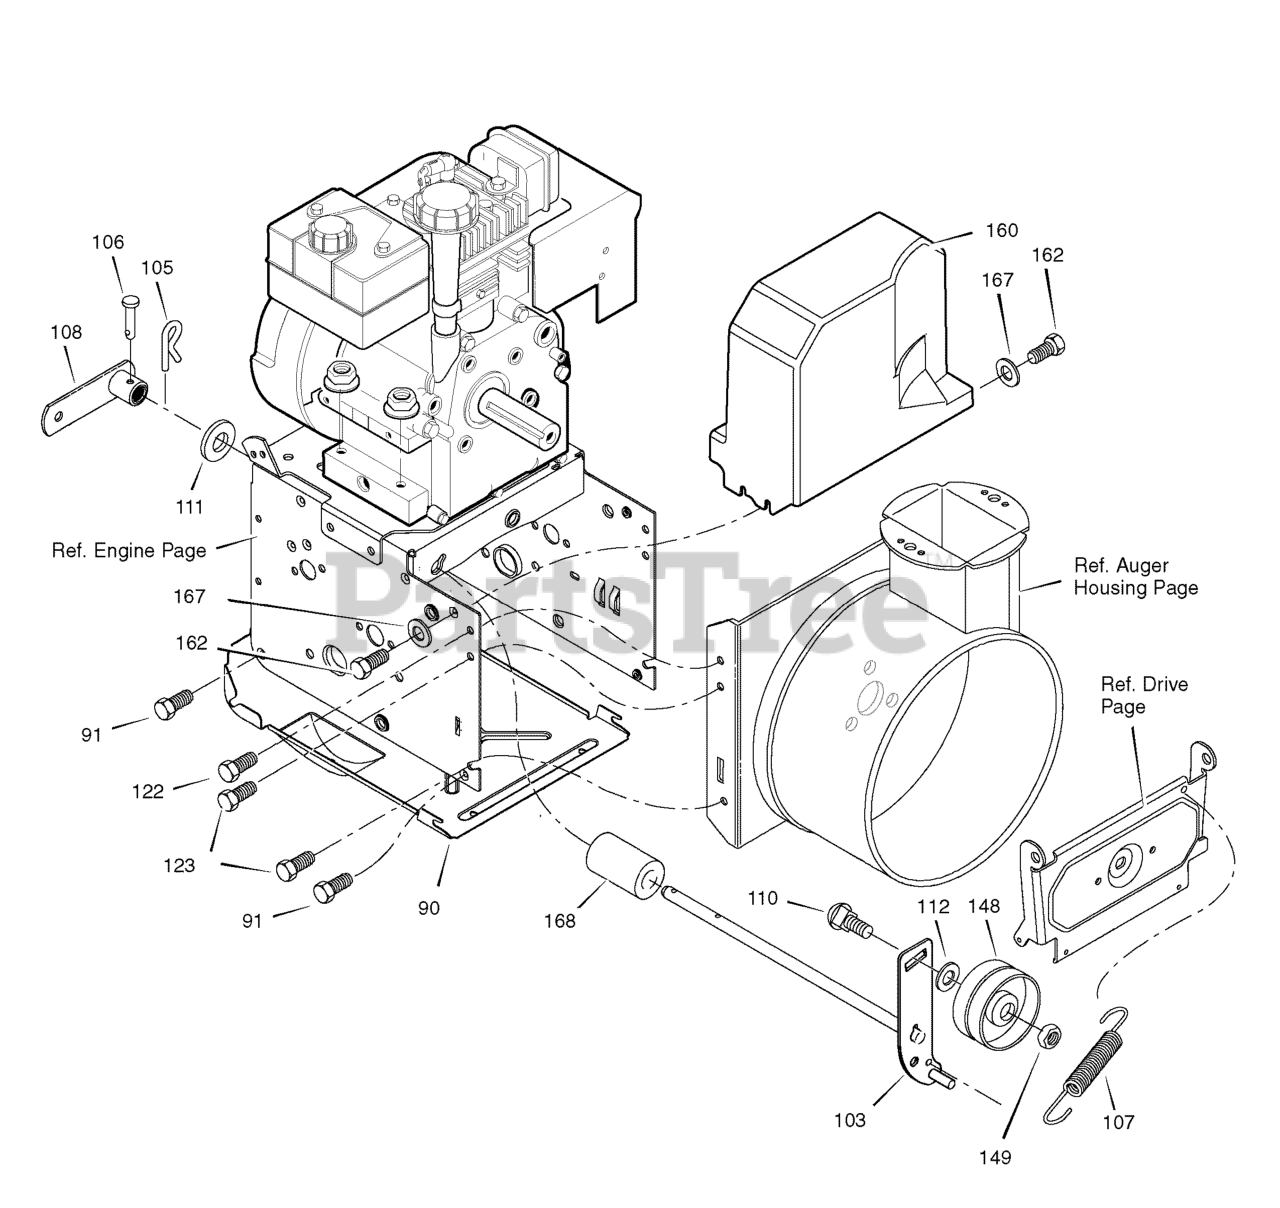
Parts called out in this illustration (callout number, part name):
90	COVER, BOTTOM
91	SCREW, 1/4-20 X .63
103	IDLER ASSEMBLY, AUGER
105	PIN, HAIR .38DIA X 1.64LG
106	PIN, CLEVIS 3/16" DIA
107	SPRING, TENSION
108	SPRING ATTACH ASSEMBLY
110	BOLT, 3/8-16 X 1.25 CARRIAGE
111	WASHER, FLAT
122	SCREW, TAP 5/16-18 X .50
123	SCREW, TAP 5/16-18 X .75
148	PULLEY, IDLER
149	NUT, JAM 3/8-16
160	COVER, BELT
162	SCREW, TAP
167	WASHER, FLAT
168	SPACER, AUGER BRACKET
